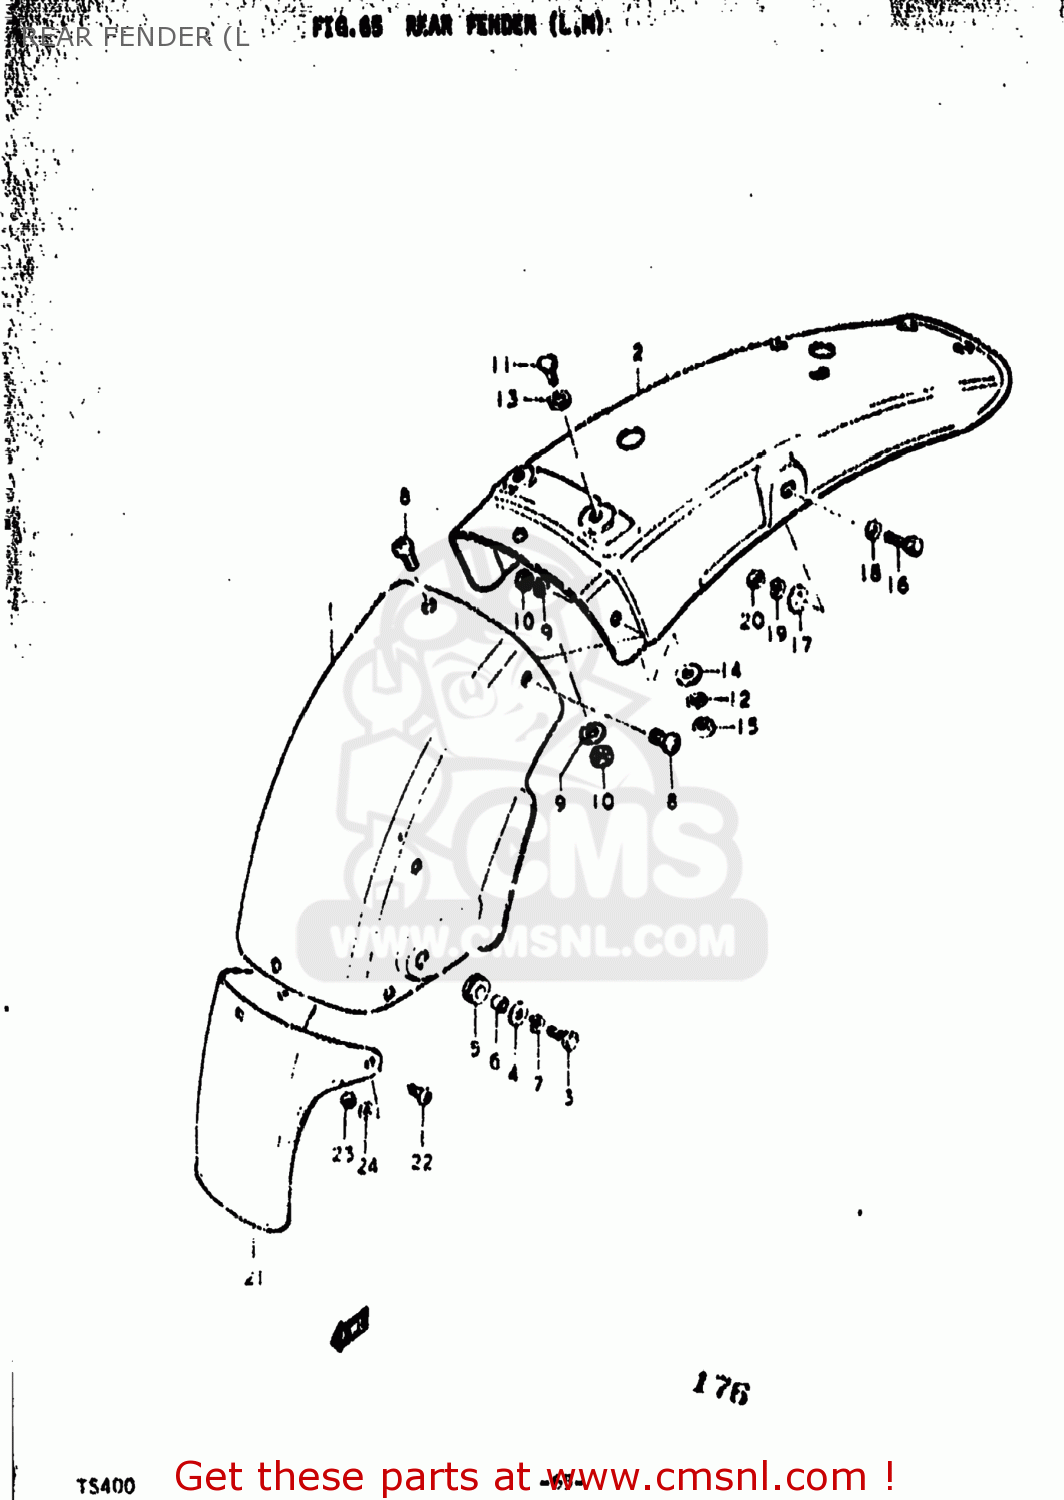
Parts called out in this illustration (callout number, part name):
1	FENDER,REAR
2	FENDER,REAR
3	BOLT
4	WASHER (6.5X20X1.2)
5	CUSHION
6	SPACER(6.1X9X7.5)
7	LOCK WASHER
8	SCREW
9	WASHER
10	NUT
11	BOLT
12	LOCK WASHER
13	WASHER
14	WASHER
15	NUT
16	BOLT
17	WASHER
18	WASHER
19	LOCK WASHER
20	NUT
21	MUD GUARD,REAR FENDER
22	SCREW
23	NUT
24	WASHER
